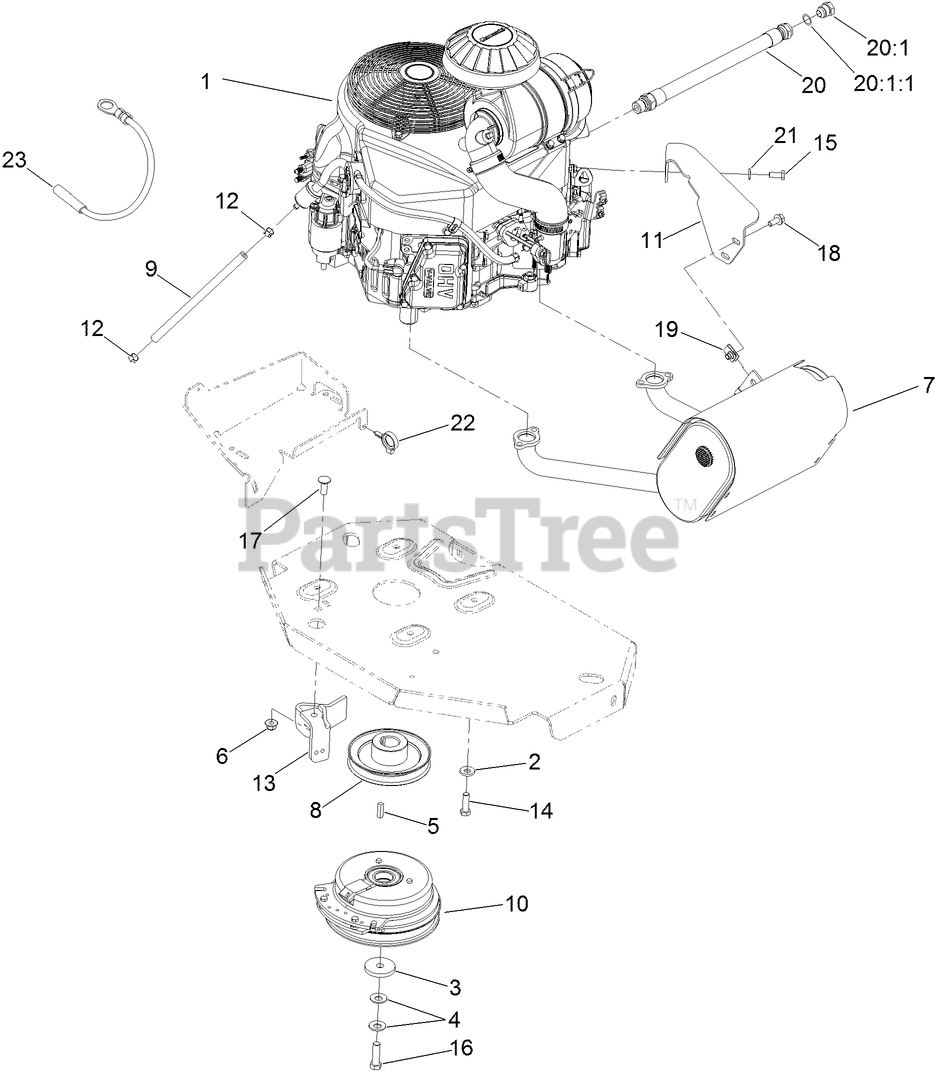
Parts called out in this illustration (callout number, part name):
2	WASHER-BELLEVILLE
3	WASHER-CLUTCH
4	WASHER-SPRING
6	NUT-HF, NI
7	MUFFLER
8	SHEAVE-PUMP, DRIVE
9	HOSE-FUEL
10	CLUTCH
11	BRACKET-MUFFLER
12	CLAMP-HOSE
13	CLUTCH-ANCHOR
14	SCREW-HH
15	SCREW-HH
16	SCREW-HH, W/LOCTITE
17	SCREW-CARR
18	SCREW-HHF
19	NUT-U
20	ENGINE OIL DRAIN HOSE ASM
20:1	PLUG-HH
20:1:1	O-RING
21	WASHER-SPRING
22	CLAMP-HOSE
23	HARNESS-GROUND, SOLENOID
